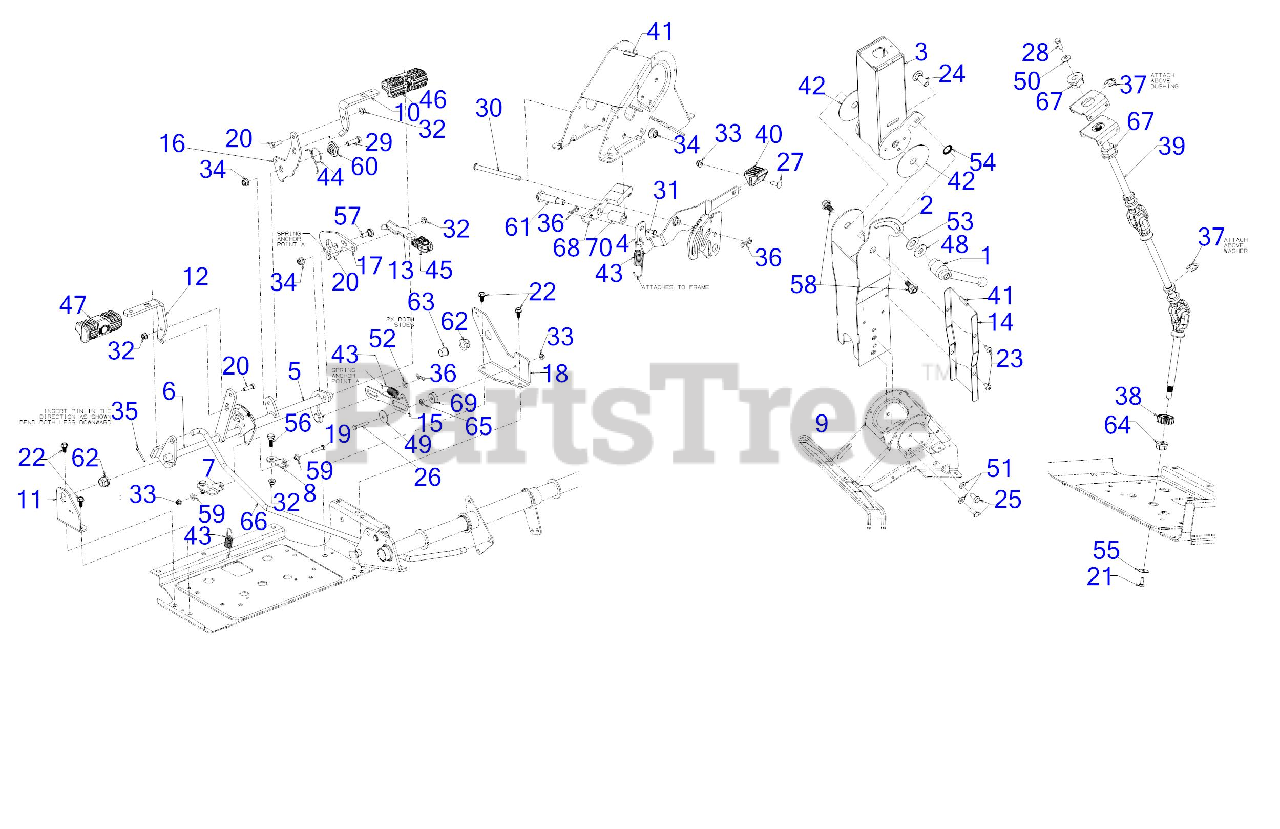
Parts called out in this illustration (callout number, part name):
1	STEERING COLUMN ADJUST LEVER
3	NUT RIVET
5	DRIVE PEDAL SHAFT ASSEMBLY
6	BRAKE SHAFT ASSEMBLY
15	NEUTRAL RETURN LINK
16	FORWARD PEDAL BRACKET
17	REVERSE PEDAL PIVOT PLATE
19	HEX SCREW 1/4-20 x 1.25
20	SCREW 5/16-18 x 1.0 GR5
21	SCREW 1/4-20 x .62 SPEC GR5
22	SCREW 5/16-18 x .750
23	SCREW 1/4-20 x .5
24	CARRIAGE BOLT 1/2-13 x 1.25 GR5
25	SCREW 5/16-18 x .62 GR5
26	SCREW 1/4-20 x 1.50 GR.5
27	SCREW 1/4-20 x .75 GR5
28	SCREW 5/16-24 x .875 GR5
29	SCREW 3/8-16 x 1.25 GR5
30	CLEVIS PIN 5/16 x 4.135
31	CLEVIS PIN .224 x .625
32	FLANGE LOCK NUT 5/16-18
33	FLANGE LOCK NUT
35	COTTER PIN-5/32 DIA
36	BOW TIE COTTER PIN 1/4-5/16
37	E-RING
38	STEERING GEAR 14T
39	COMPLETE STEERING SHAFT
39	FLAT WASHER
40	CRUISE TILT KNOB
42	COLUMN PLATE
43	EXTENSION SPRING
44	TORSION SPRING
45	REVERSE PEDAL PAD
46	FORWARD PEDAL PAD
47	BRAKE PEDAL PAD
48	FLAT WASHER
49	FLAT WASHER
50	BELL WASHER .337 X.867 x .057
51	FLAT WASHER
52	WASHER THRUST .375X.70X.030
53	FLAT WASHER NYLON 5/8
54	LOCK WASHER
55	FLAT WASHER
56	SHOULDER SCREW .437
57	SHOULDER SCREW
58	SHOULDER SCREW .625X.165X3/8-16
59	SHOULDER SPACER
60	SHOULDER SPACER 1.50X.38X.38
61	SHOULDER SCREW .496X1.44 3/8-16
62	FLANGE BEARING
63	NYLINER BEARING
64	FLANGE BEARING
65	BALL BEARING .25 X .625
66	FRONT BRAKE ROD
67	FLANGE BEARING
68	CRUISE LATCH
69	SPACER .267X1.00X.36
70	SPACER 0.510 X 0.775 X 1.190
